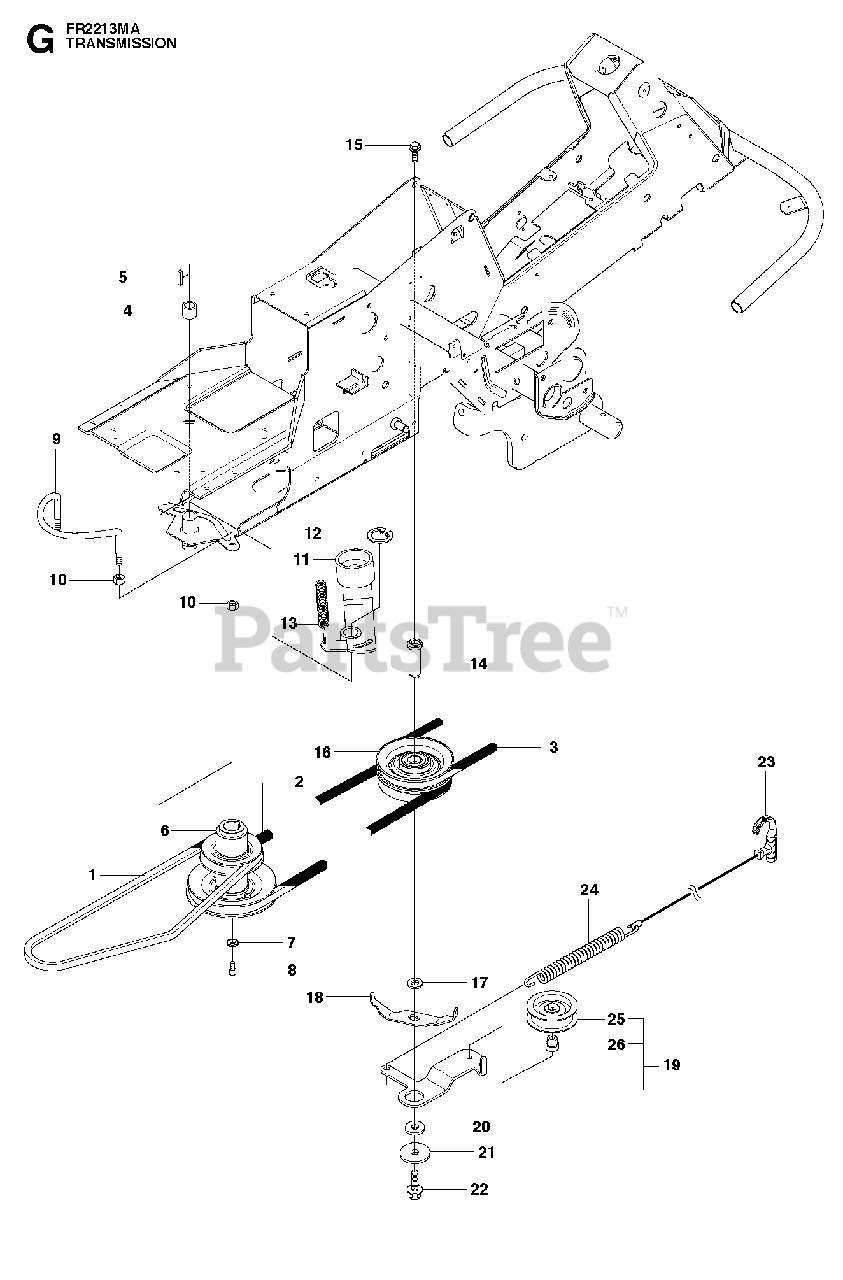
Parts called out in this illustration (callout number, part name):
1	BELT
2	BELT
9	BELT GUIDE
11	TENSIONER
12	RETAINING RING SGA 25
14	SHAFT
18	BELT GUIDE
22	BOLT
25	PULLEY
26	BUSHING
